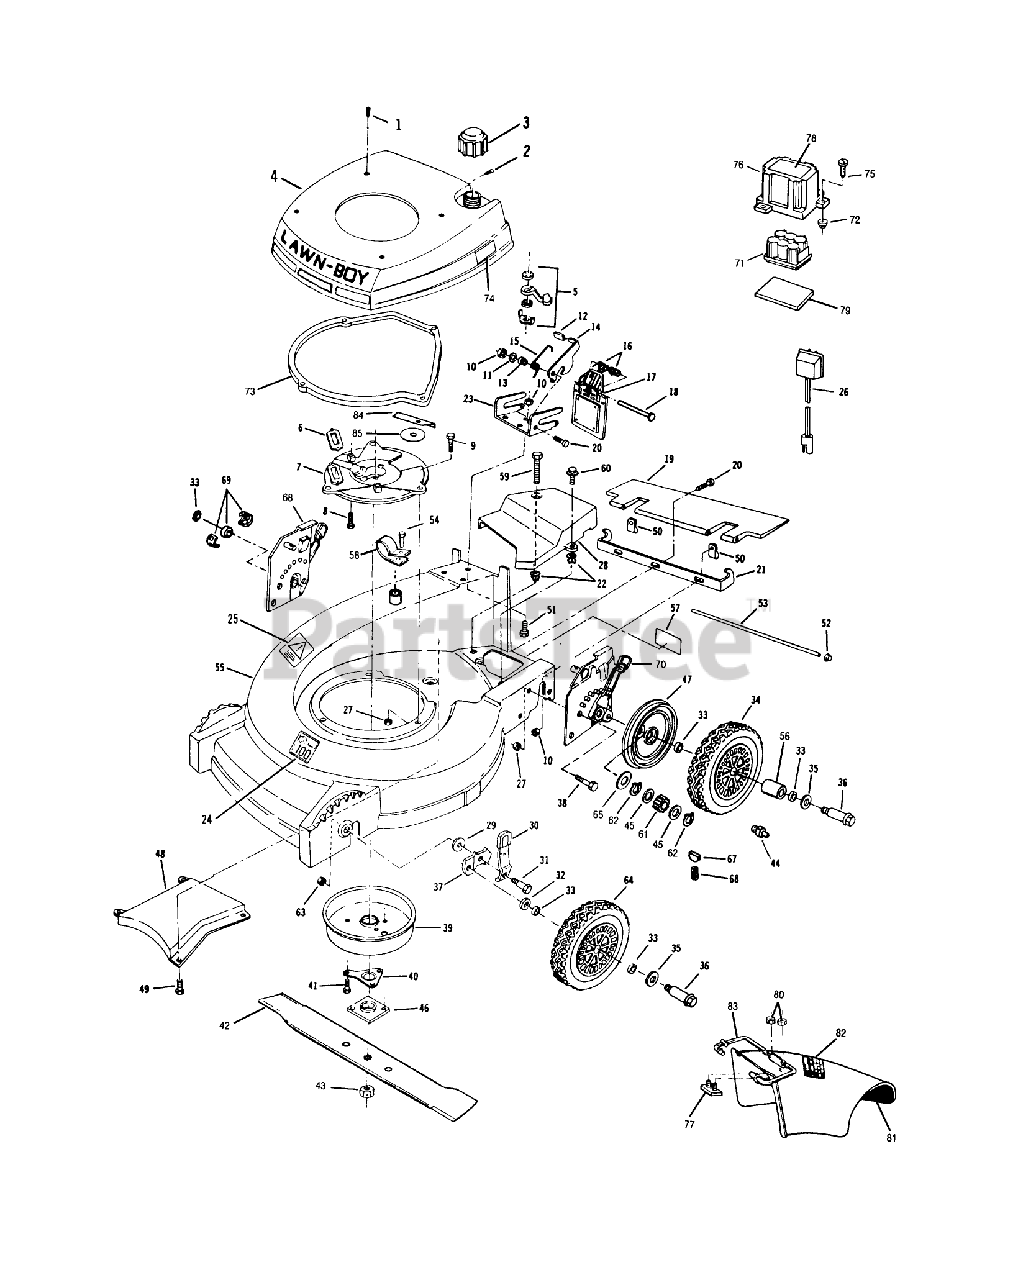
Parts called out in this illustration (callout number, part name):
1	SCREW LAWRENCE
2	SCREW S
3	FUEL CAP & INSERT
8	SCREW V
9	SCREW-HH
10	LOCKNUT E
12	KNOB (S&R)
15	SPRING
16	SPRING ASOC
18	ROD (RB&W)
19	T/SHIELD SM&P
27	NUT-LOCK F
29	WASHER
30	SPRING ARM ASM
31	BOLT
32	WASHER WROUGHT
33	WASHER
35	SPACER
36	BOLT WHEEL
39	MUFFLER COVER F
40	SUPPORT F
41	SCREW
43	NUT-BLADE
44	FITTING LINCOLN
45	SPACER/GR ALGHNY
46	PLATE AND COLLAR ASM
48	BAFFLE CHUTE PL
54	SCREW LAWRENCE
60	SCREW
61	PINION BROCKWAY
62	RET RING
63	LOCKNUT
64	WHEEL&TIRE 8" TRI
65	THRUST WASHER
66	KEY
67	SPRING
69	REAR AXLE BEARING
72	NUT-CLIP
75	SCREW - SELF TAPPING
79	PAD-BATTERY
80	LOCKNUT E
83	LATCH BAR ARGO
